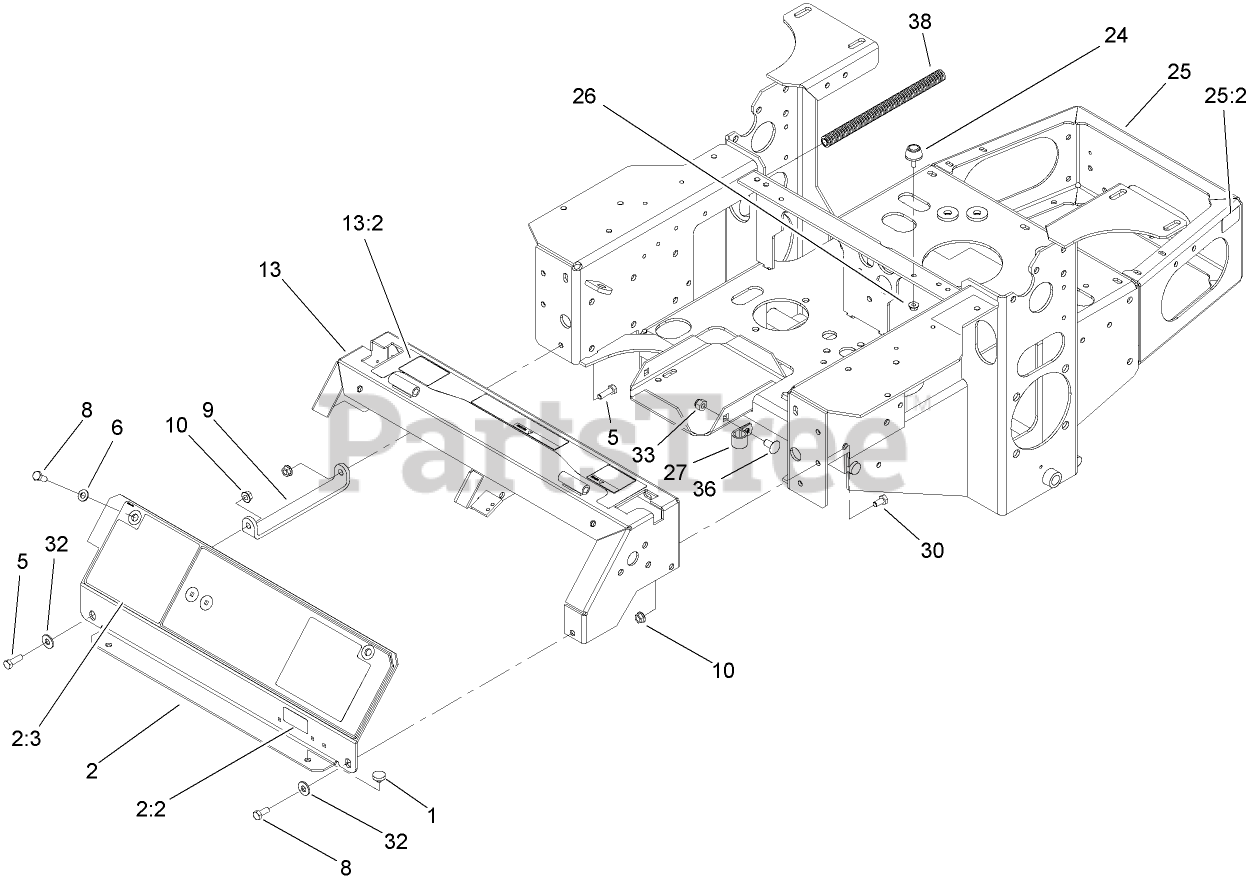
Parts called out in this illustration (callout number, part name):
1	BUMPER
2	PANEL ASM
2:2	DECAL-PROTECTION, EAR
2:3	DECAL-COVER, PANEL
5	SCREW-HH
6	WASHER-PLAIN
8	SCREW-HH
9	BRACKET-PANEL, INSTRUMENT
10	NUT-HF
13	CONSOLE ASM
13:2	DECAL-WARNING
24	BUMPER-RUBBER
25	MAIN FRAME ASM
25:2	DECAL-SURFACE, HOT
26	NUT-HF
27	CLIP-LOOM
30	SCREW-HH
32	WASHER-FLAT
33	NUT-LOCK, NI
36	SCREW-CARR
38	CONDUIT-CONVOLUTED, SPLIT
